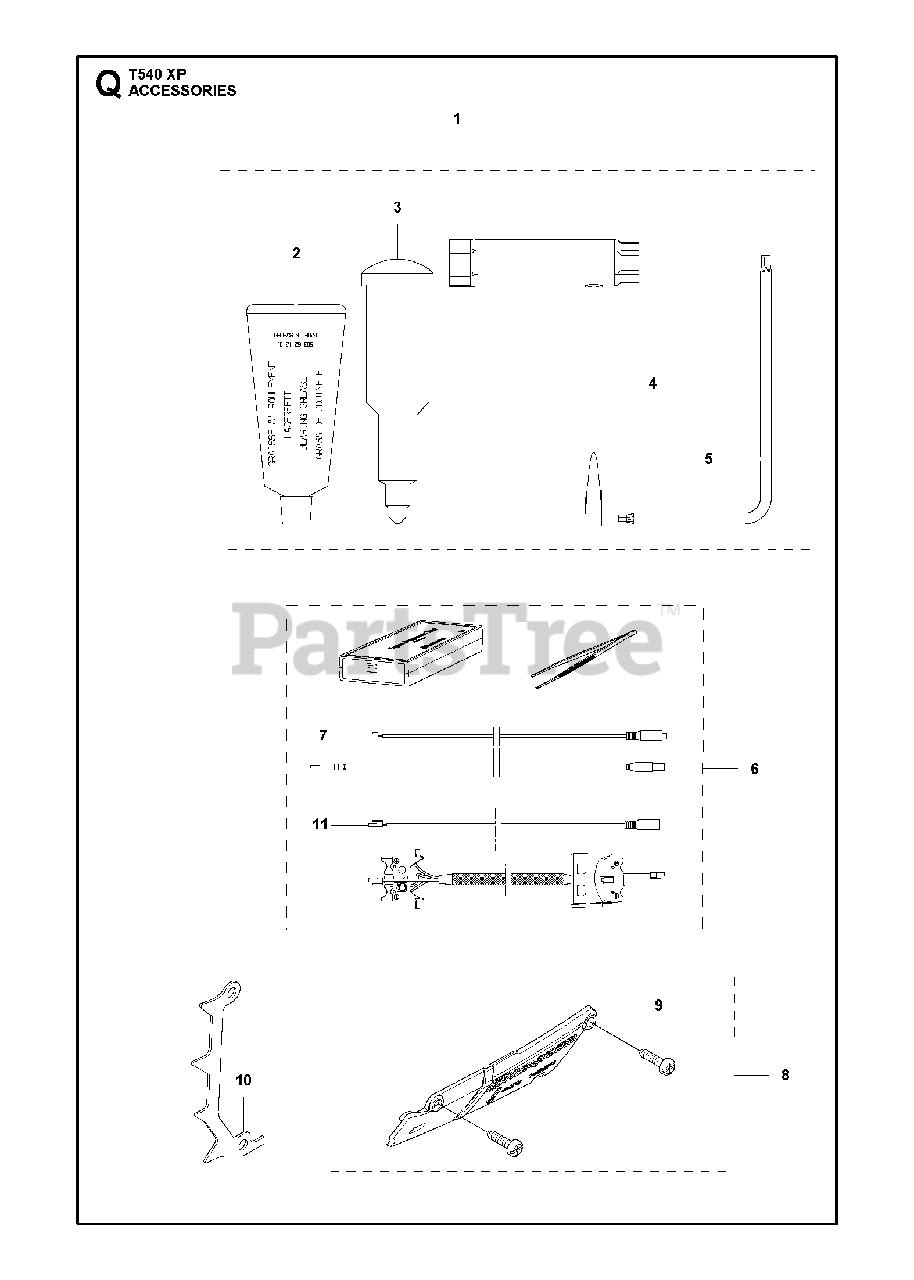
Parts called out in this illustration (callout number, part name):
2	GREASE
3	Grease Gun
4	COMBINATION WRENCH
6	DIAGNOSTIC TOOL KIT
7	CABLE ASSY
8	WINTER KIT
9	SCREW
11	CABLE ASSY
